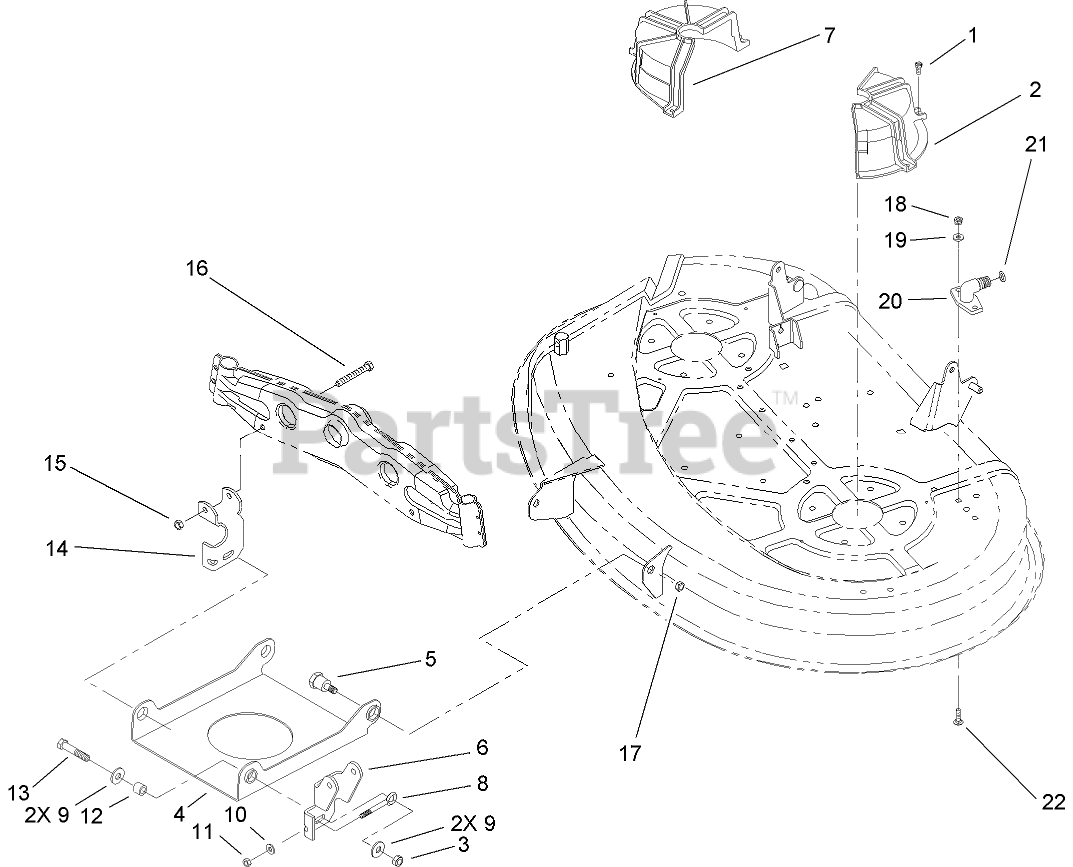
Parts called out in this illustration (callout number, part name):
1	SCREW-HWHTF
2	GUIDE-BELT, LH
3	NUT-LOCK, NI
4	PAN-DECK SUSPENSION, FRONT
5	BOLT-SHOULDER, HH
6	BRACKET-SUSPENSION, LH
7	GUIDE-BELT, RH
8	SCREW-ADJUSTING
9	WASHER-HARDENED
10	WASHER-FLAT
11	NUT-LOCK, NI
12	SPACER
13	SCREW-HH
14	BRACKET-SUSPENSION, RH
15	NUT-LOCK, NI
16	SCREW-HH
17	NUT-LOCK, NI
18	NUT-LOCK, NI
19	WASHER-FLAT
20	FITTING-WASHOUT
21	O-RING
22	BOLT-CARR
